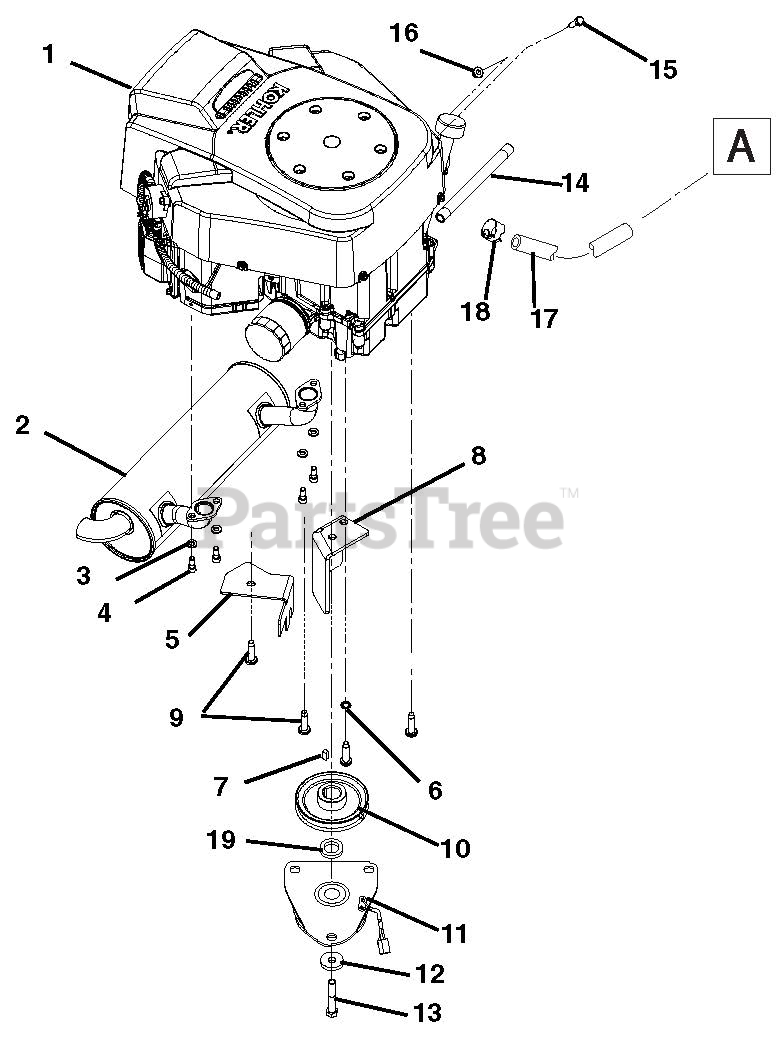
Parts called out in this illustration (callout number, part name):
1	ENGINE, COURAGE 25HP
2	MUFFLER, KOHLER TWIN
3	@WSHR-LK .31X.078 REG YWZC
4	SCR-CAP .31-18X.75 S/HD
5	GUARD, HD CLUTCH WIRE
6	@WSHR-LK-EXT.391X.628X.036YWZC
7	KEY-SQ .25X.625X.25 SAE 8630
8	ANCHOR - OGURA CLUTCH - HD
9	BLT, TAP .38-16X1.5 PH TRX YZ
10	SHEAVE, 4.831 X 1.002 ENGINE
11	CLUTCH ASSY, OGURA# GT1A-HU02
12	WSHR-FL-STL .469X2.00X.25 YWZC
13	BLT-HEX .44-20X2.50 G5 YZ EP80
14	HOSE, HYD .38-11-0K M6N0-F6J0
15	@BLT-HEX .31-18X1.00 GR5 YWZC
16	@NUT-LK-NYL-FLG .31-18 YWZC
17	HOSE, .25 LOW-PERM BULK GAS
18	CLAMP, FUEL LINE
19	SPACER 1.002ID X 1.75 OD X.266
